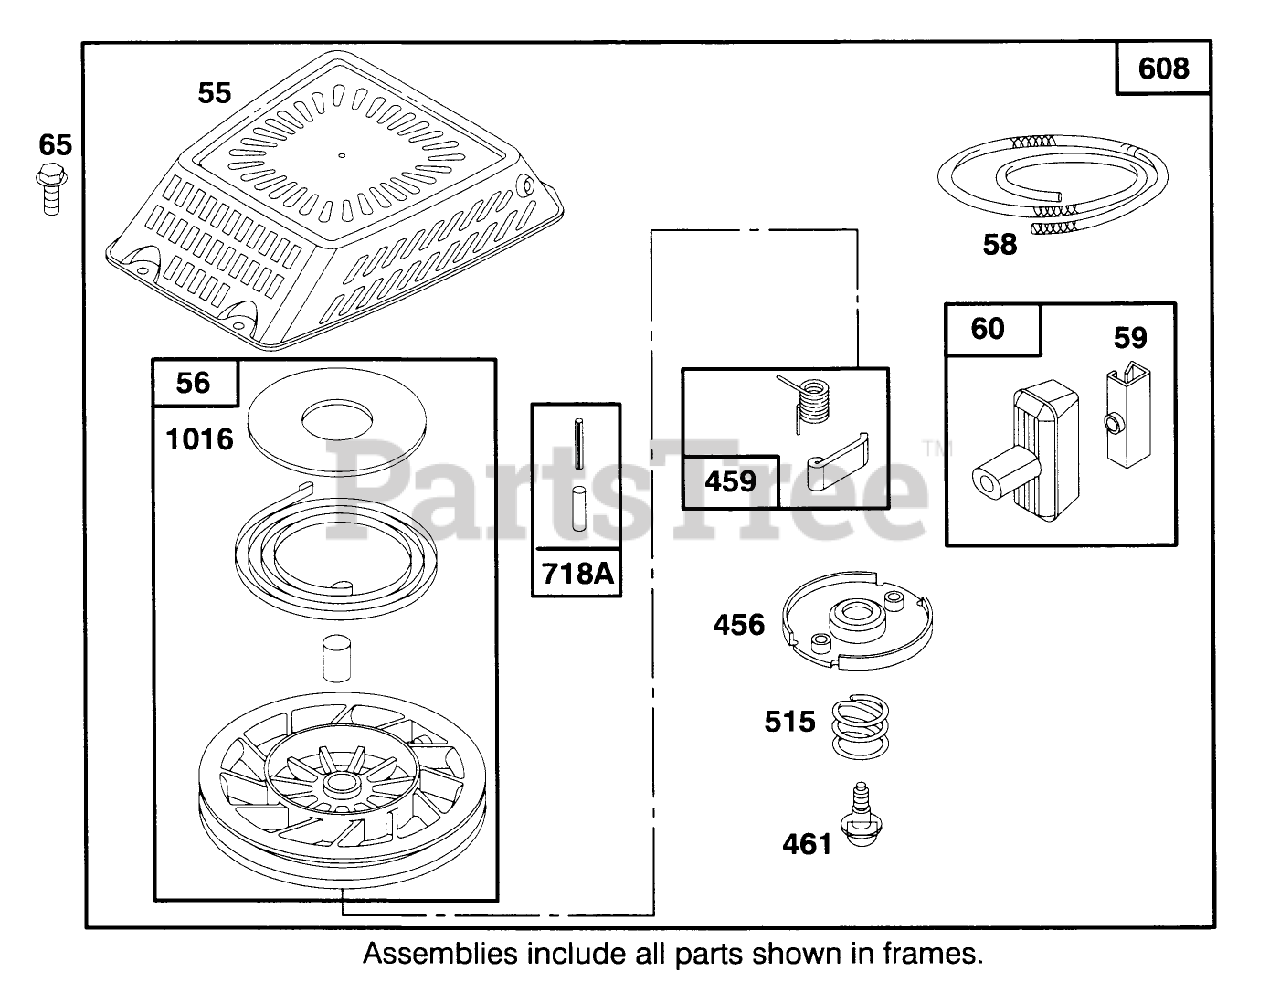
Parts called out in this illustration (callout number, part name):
60	HANDLE-REWIND STARTER
456	RETAINER - SPRING
515	SPRING - RETAINER
